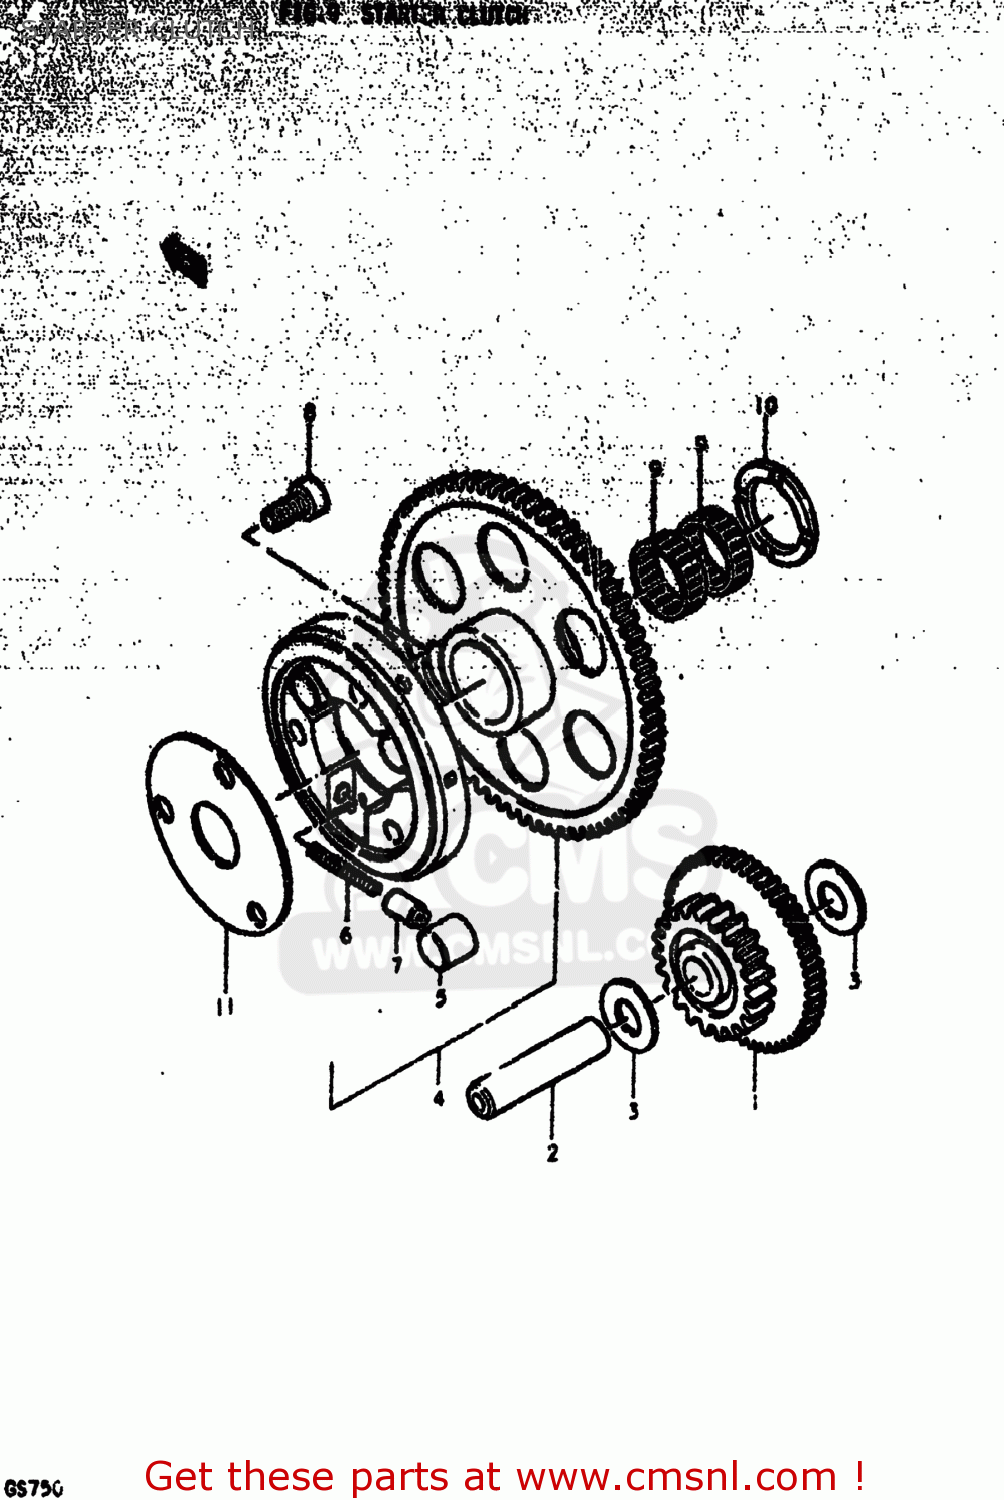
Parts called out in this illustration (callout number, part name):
1	GEAR,STARTER IDLE
2	PIN(7.4X13X56)
3	WASHER(13.3X25X0.85)
4	CLUTCH SET,STARTER
5	ROLLER(15X13)
6	SPRING
7	PIECE,PUSH
8	BOLT
9	BEARING(25X29X9.9)
10	WASHER(25X38X2.5)
11	SHIM,STARTER CLUTCH HUB
